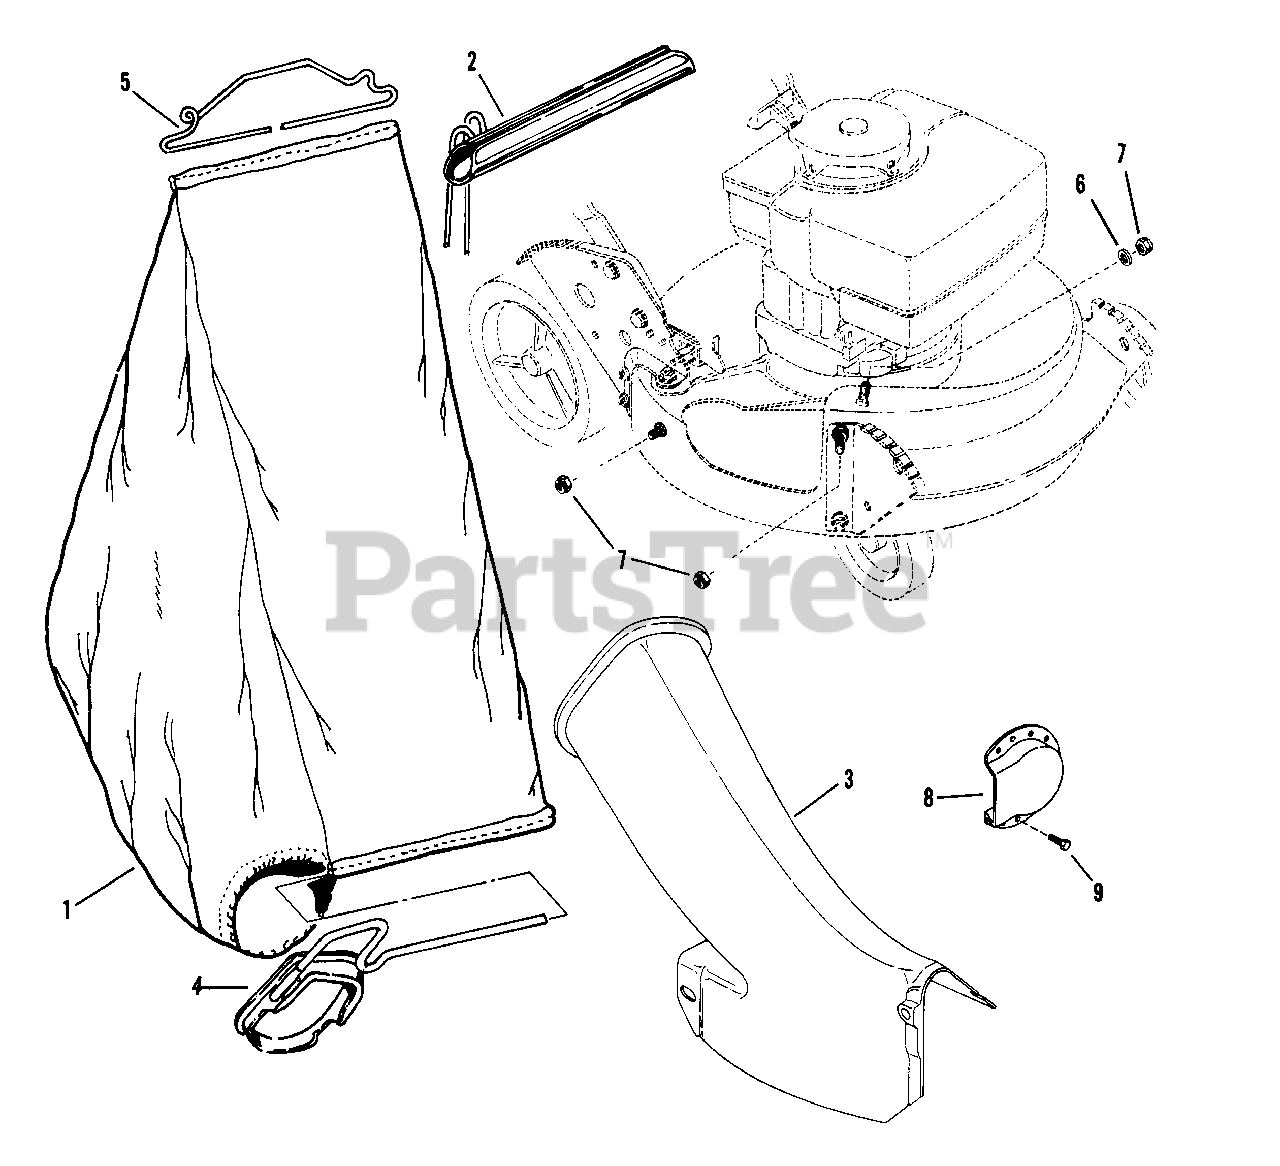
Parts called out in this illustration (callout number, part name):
1	BAG, Grass (COMMERCIAL ONLY)
2	ASSEMBLY, Rope & Slider
3	ADAPTER, Bag
4	CONNECTOR, Bag
5	WIRE, Bag Connector
6	WASHER, 5/16 Flat
7	NUT, 5/16-18 Hex Flange Lock
8	DEFLECTOR, Muffler (Briggs)
9	SCREW, #8-18 x 3/8" Hex Head Cap
